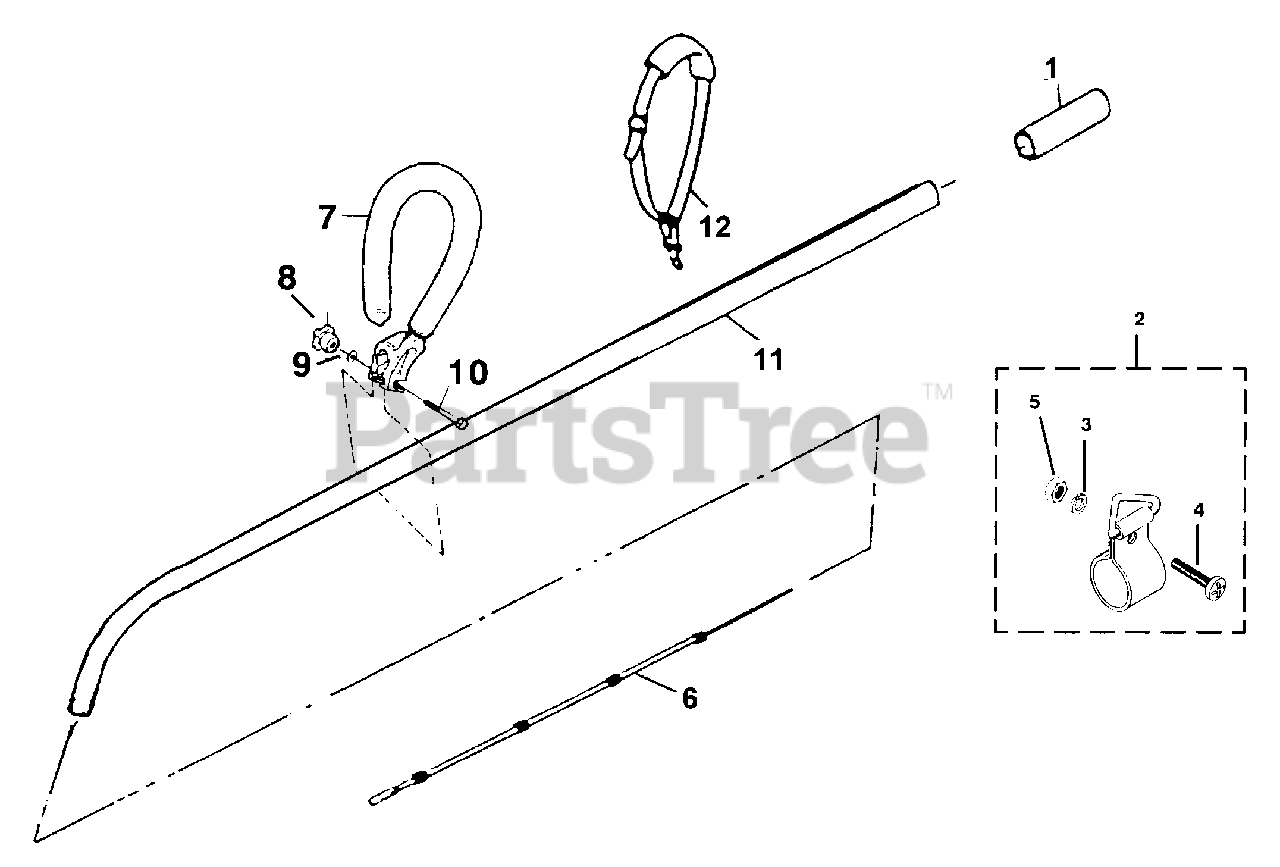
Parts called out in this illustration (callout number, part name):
1	FOAM GRIP
2	HANGER ASSY
5	NUT
6	FLEX SHAFT
7	HANDLE ASSY.
11	TUBE ASSY
12	HARNESS
